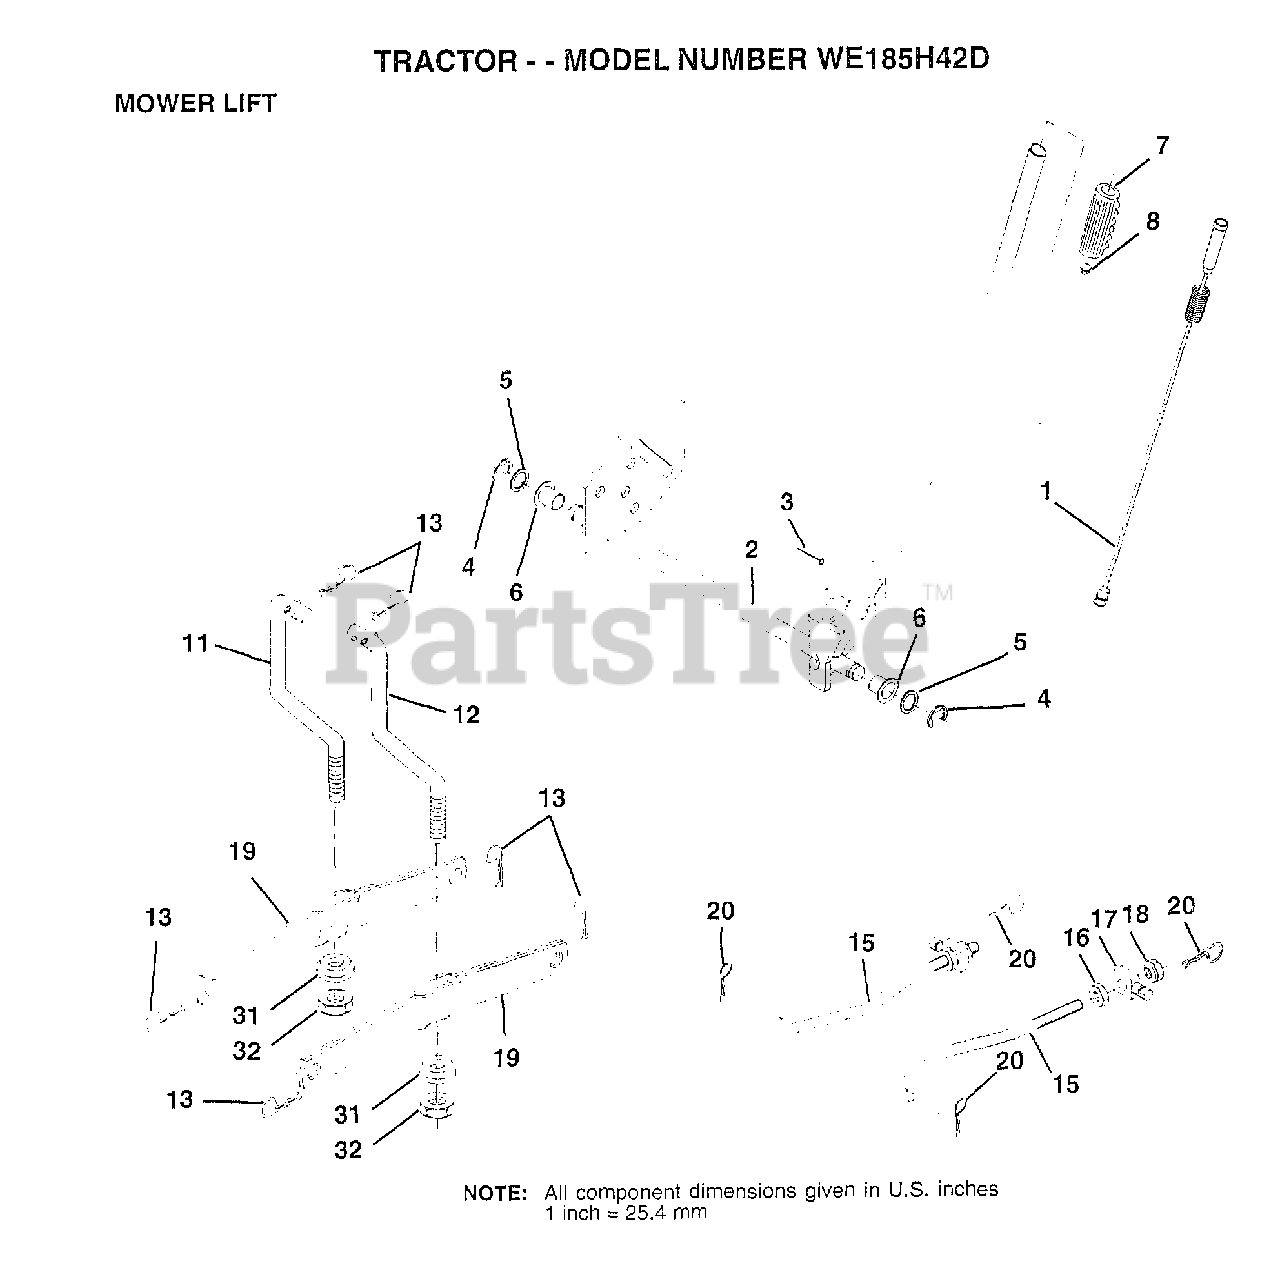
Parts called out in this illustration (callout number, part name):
1	WIRE ASM W.SPRING
2	"SHAFT ASM LIFT,RH"
3	PIN-GROOVE LT
5	WASHER
6	NYLON BEARING
7	GRIP
15	LINK.FRONT
16	NUT
17	TRUNION
18	NUT.LK.W/WSH.1/2.
19	ARM SUSP REAR
20	RETAINER.SPRING
31	BEARING PVT LH
32	NUT.CROWNLOCK.3/8
